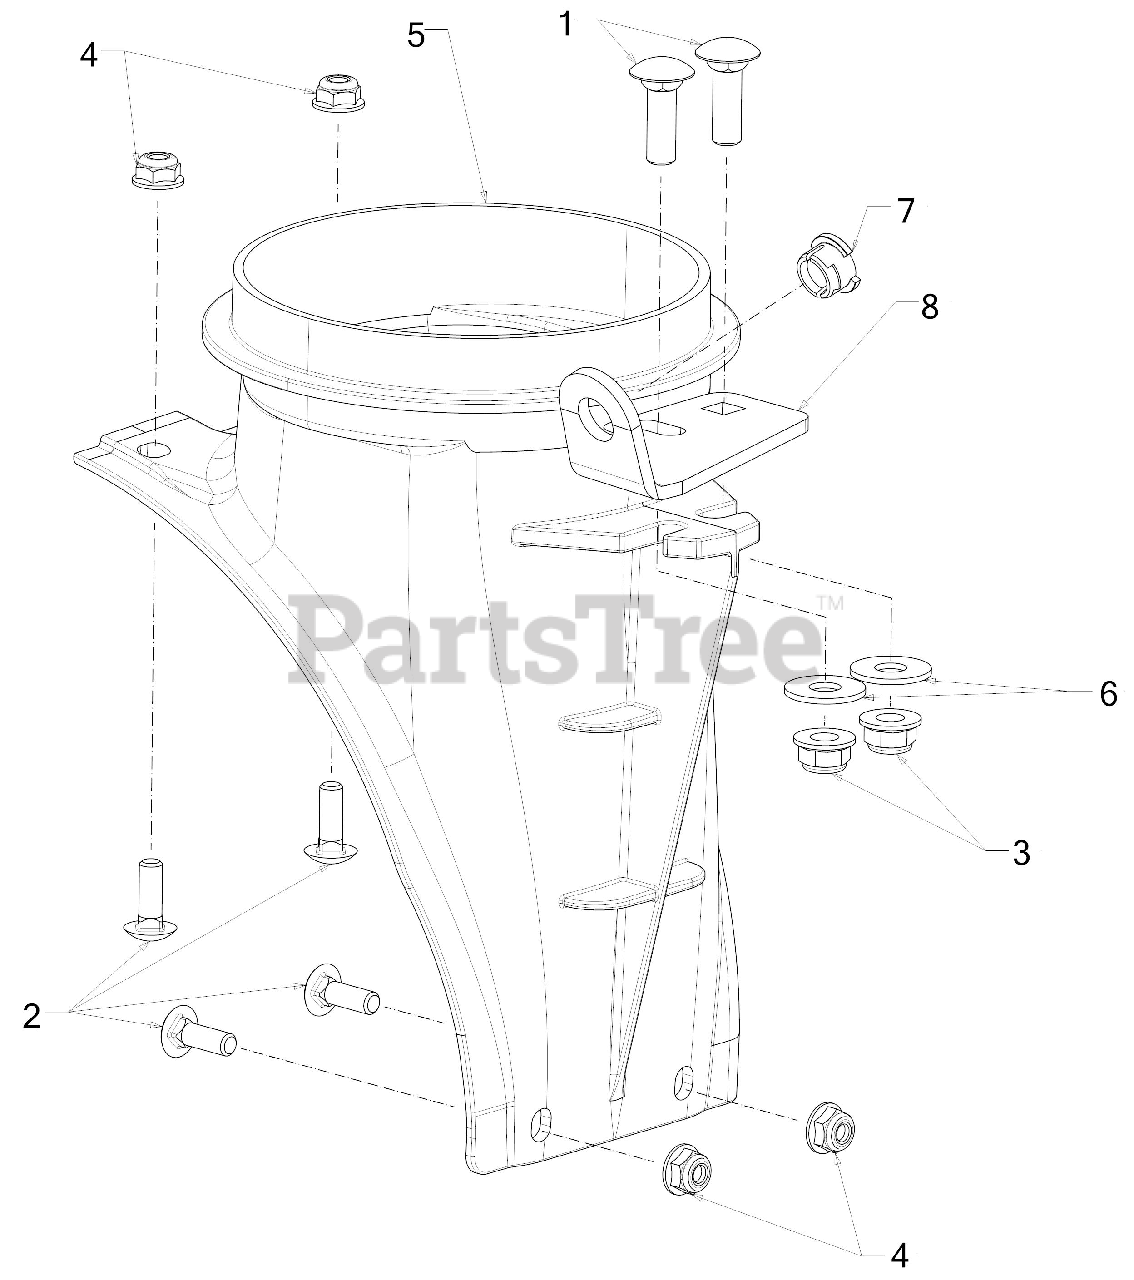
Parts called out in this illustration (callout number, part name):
1	CARRIAGE BOLT 5/16-18 x 1.00
2	SCREW 1/4-20 x .75 GR5
3	FLANGE LOCK NUT 5/16-18
4	FLANGE LOCK NUT
5	CHUTE ADAPTER
6	FLAT WASHER
7	BUSHING .380 ID
8	CHUTE CRANK BRACKET
